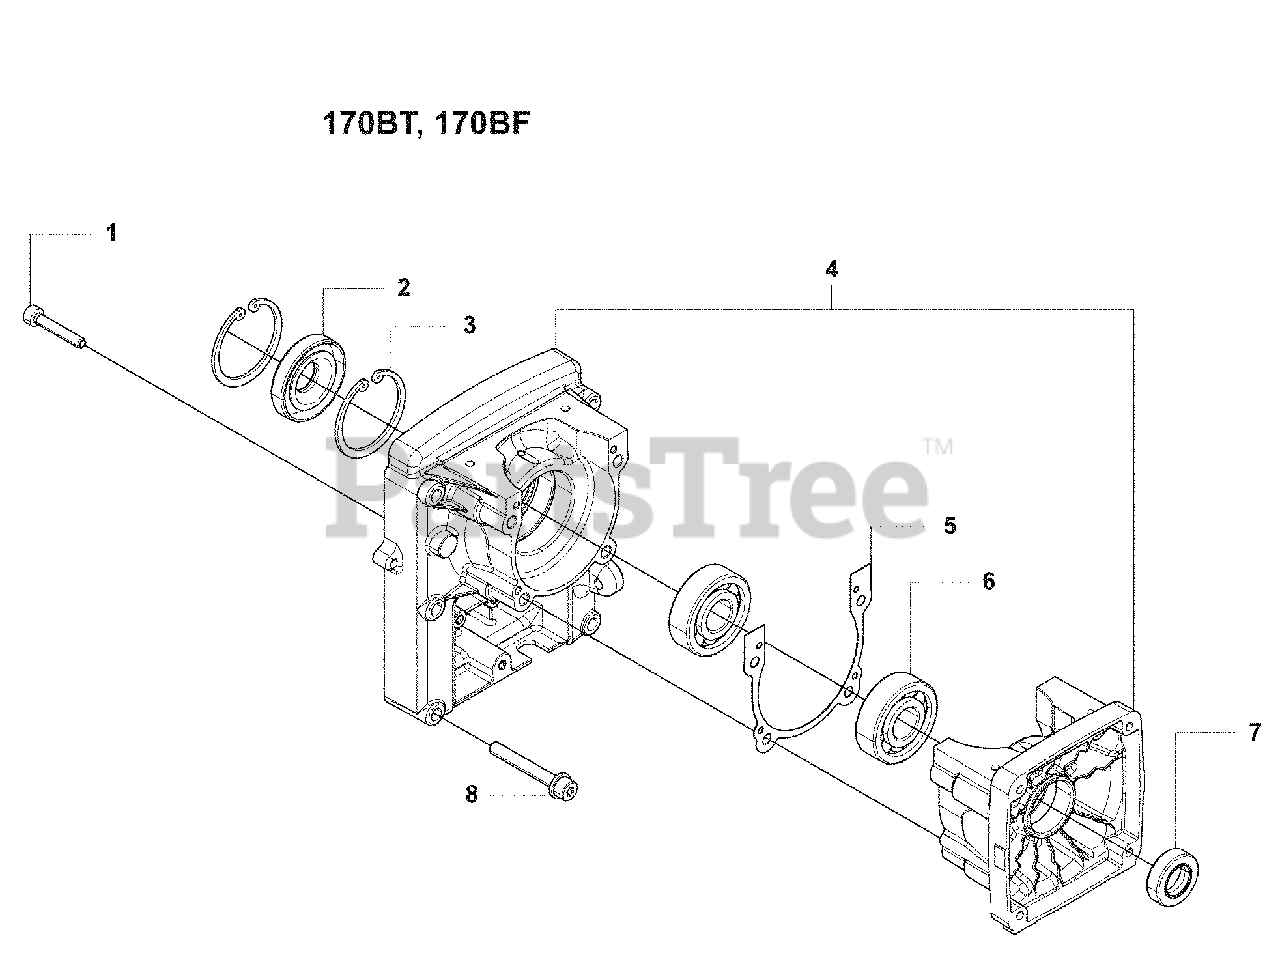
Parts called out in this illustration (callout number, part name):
1	Bolt
2	Seal
3	Snap Ring
4	CRANKCASE-C
5	Gasket
6	Ball Bearing
7	Seal
8	Bolt
